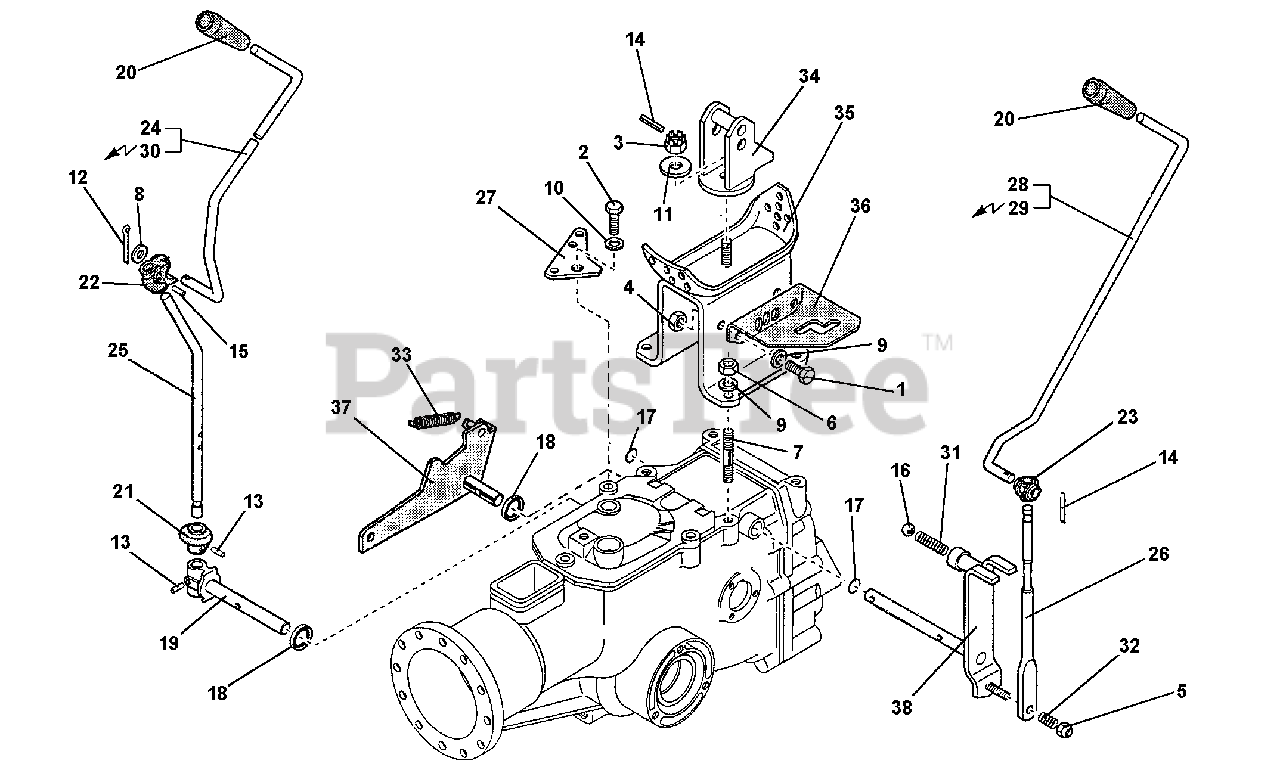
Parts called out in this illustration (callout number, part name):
1	SCREW, M8X20
2	SCREW, M8X30
3	NUT, CASTLE, M12
5	NUT, SELF LOCKING, M8
7	STUD, M8X38X14X20
8	WASHER, M10.5
9	SUPER WASHER
10	WASHER, LOCK, M8.4
11	LOCK WASHER, M13
13	PIN, LOCKING, M4X20
14	PIN, LOCKING, M3X22
15	PIN, LOCKING, M4X24
16	BALL, 15/32"
17	OIL SEAL, 14X18X2.5
18	OIL SEAL, 14X22X4
21	PTO STOP RING
22	PTO ARTICULATION
23	SPEED ARTICULATION, 716, 720, 730
24	PTO CONTROL ROD, RECOIL START
25	PTO CONTROL LEVER
26	SPEED CONTROL LEVER
27	REVERSE BRACKET
28	SPEED CONTROL ROD, RECOIL START
29	SPEED CONTROL ROD, ELECTRIC START
30	PTO CONTROL ROD, ELECTRIC START
34	HANDLE BAR SUPPORT
35	HANDLE BAR ANCHOR
36	GEAR SELECTOR, 716, 720, 730
37	REVERSE LEVER
38	SPEED CONTROL LEVER, 716, 720, 730
